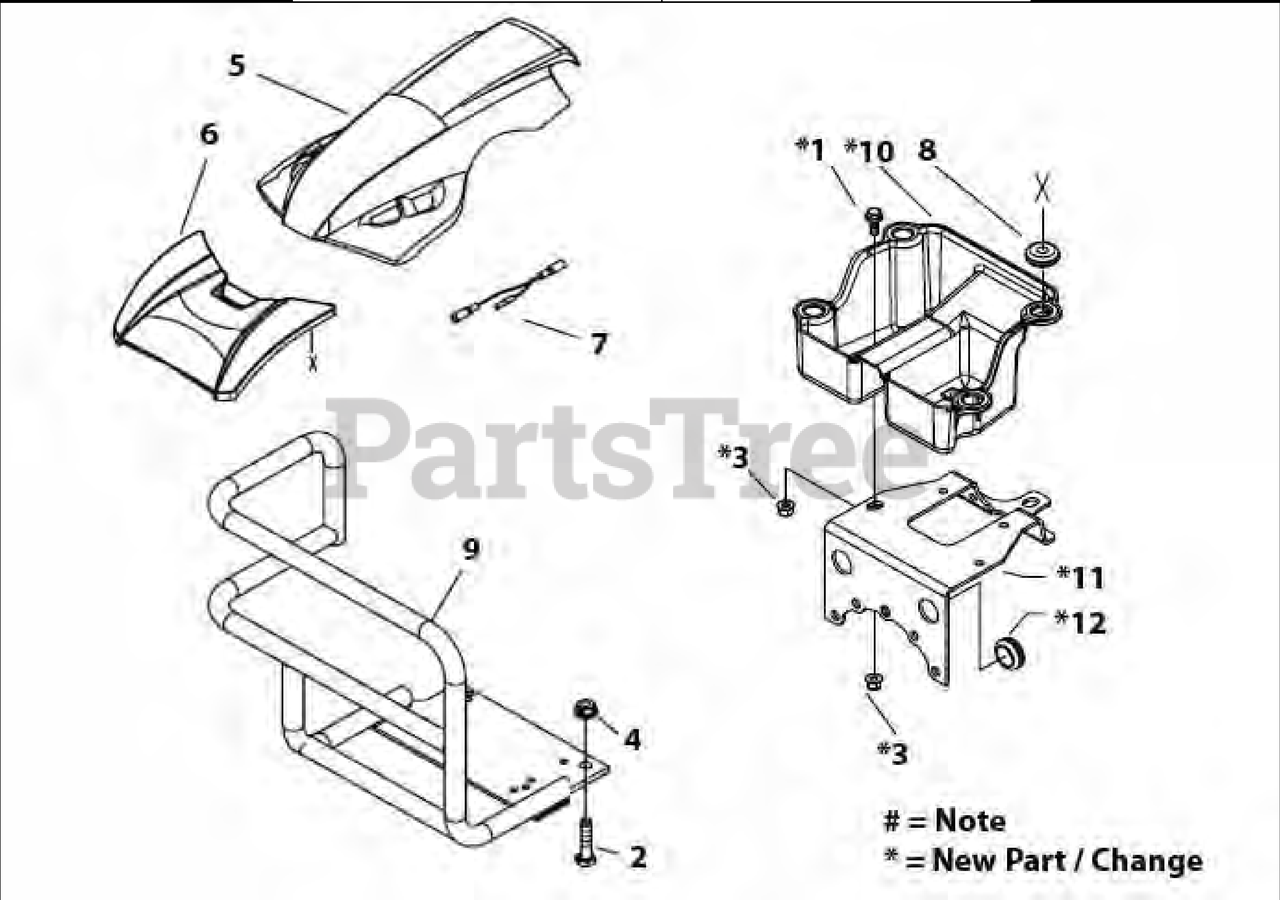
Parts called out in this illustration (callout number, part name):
1	SCREW TE C/F M6X20 DIN 6921-8G
2	CAPSCREW M8X40 UNI5739-8G
3	LOCKNUT M6 FLANGED
4	LOCKNUT M8 FLANGED
5	STEERING COLUMN COVER
6	LOWER COVER (RECOIL START ONLY)
7	OPC WIRE
8	SUPPORT BODY CAP / GROMMET
9	BUMPER GX340 – GX390
10	TRAY
11	SUPPORT BRACKET
12	CABLE GLAND/ GROMMET
